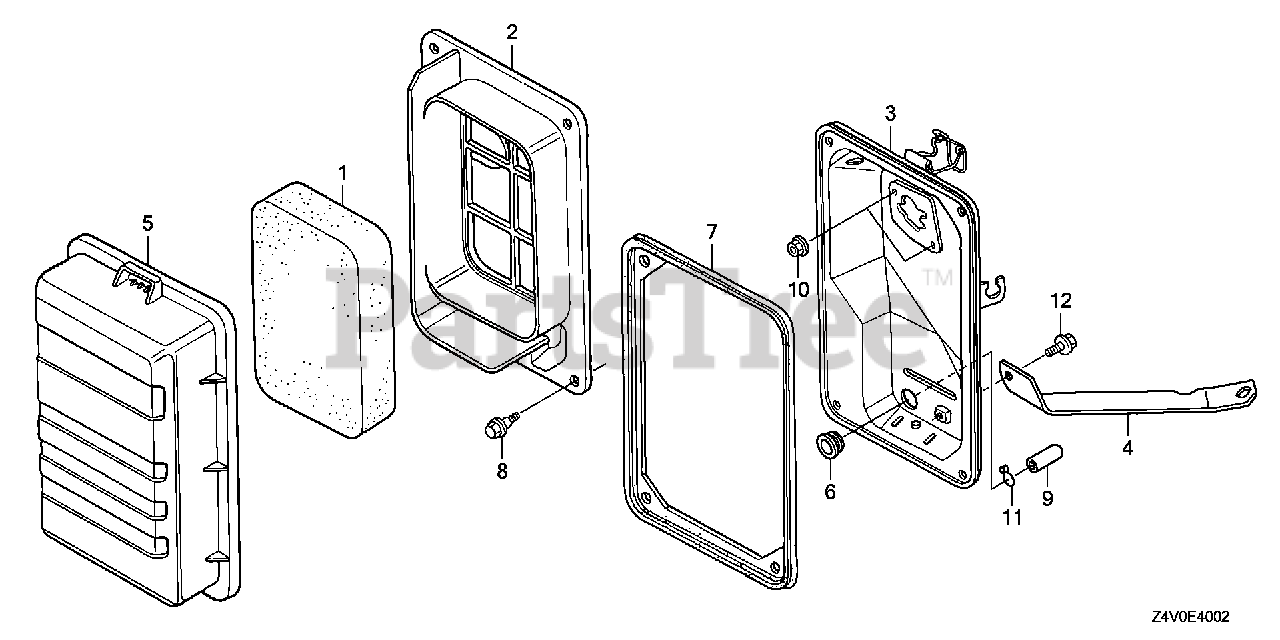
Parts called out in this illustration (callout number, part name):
1	ELEMENT, AIR CLEANER
2	SEPARATOR, AIR CLEANER
3	HOUSING, AIR CLEANER
4	STAY, AIR CLEANER
5	COVER, AIR CLEANER
6	GROMMET, AIR CLEANER
7	SEAL, AIR CLEANER
8	BOLT, TURN SIGNAL SETTING
9	CAP, SEALING
10	NUT, FLANGE (6MM)
11	CLIP, TUBE (B10)
12	BOLT, FLANGE (6X10)
